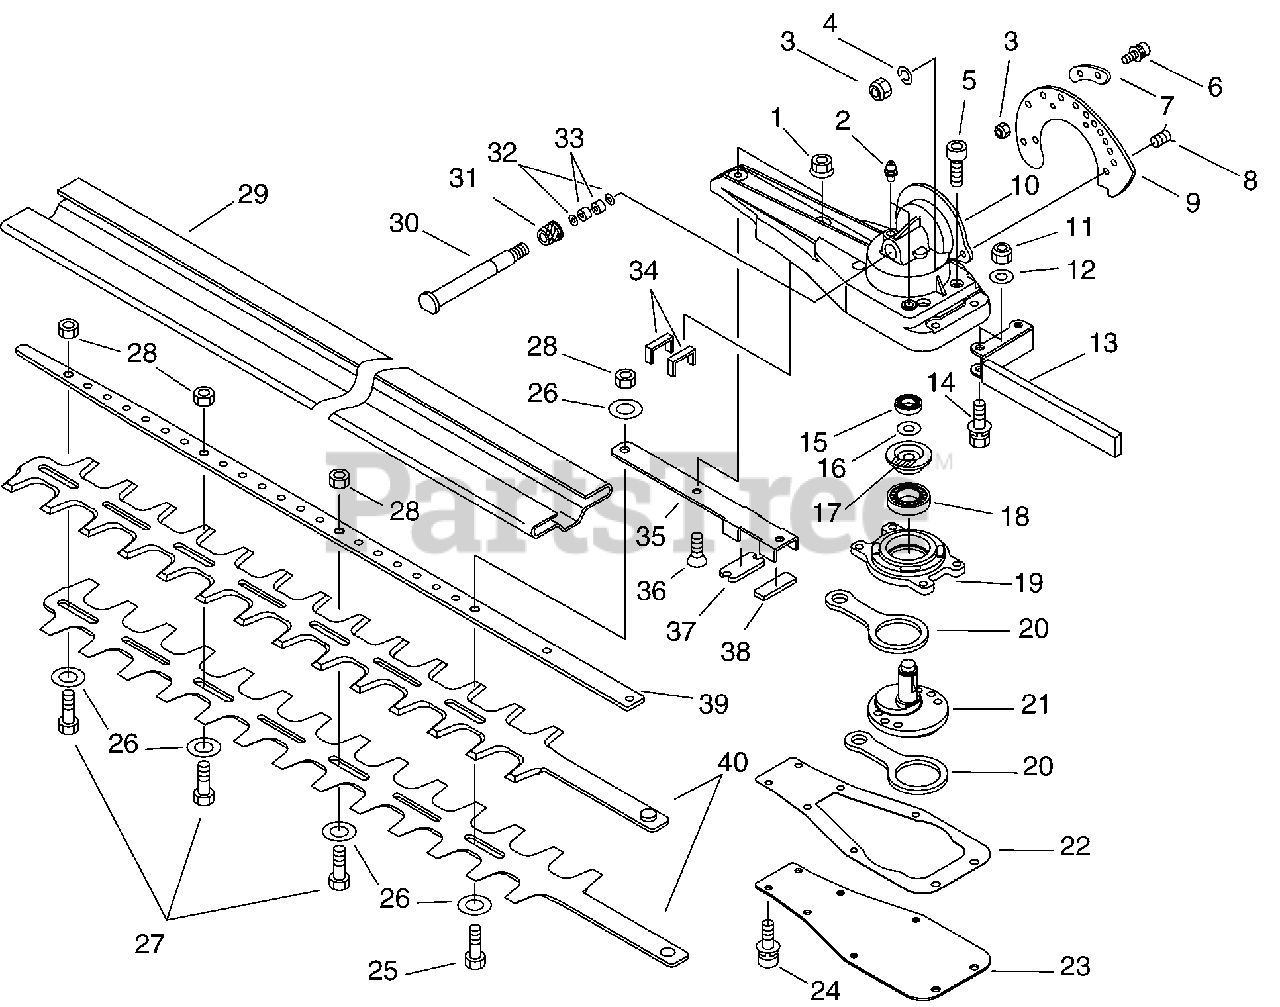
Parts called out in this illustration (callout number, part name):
1	PIN, COTTER 6×18
3	WASHER 8
4	WASHER, CONICAL
6	GASKET, GEAR CASE
7	RING, RETAINING
8	COLLAR 8
9	SPRING, COMPRESSION
10	LINCHPIN
11	RING, SNAP Ø22
12	RING, SNAP
13	BEARING, BALL 6900
14	GEAR, BEVEL
16	BOLT 5×25
17	SCREW 5×12
18	CASE, GEAR
20	O-RING 32
